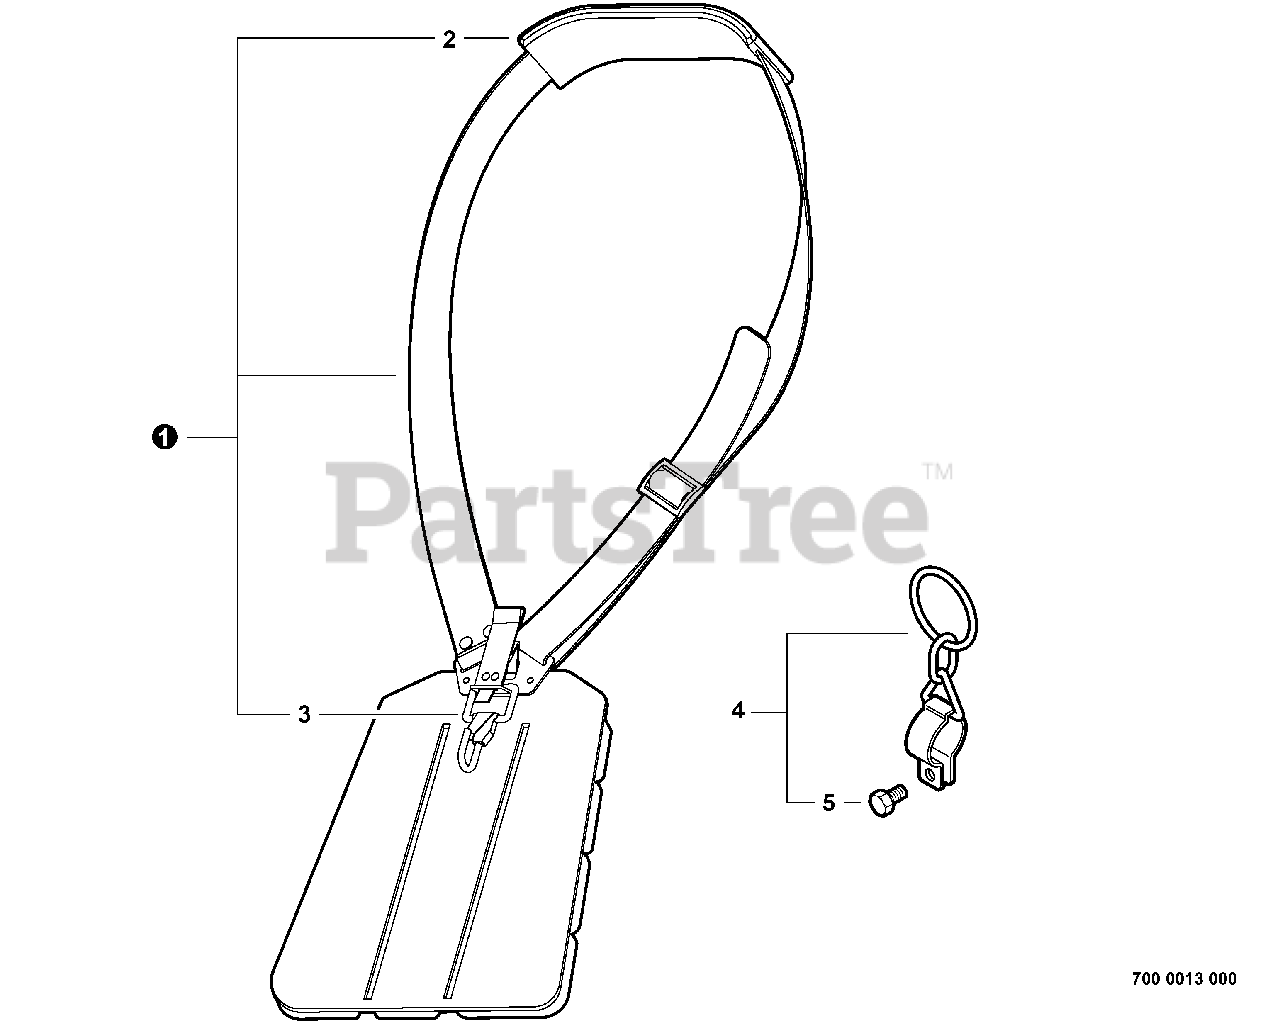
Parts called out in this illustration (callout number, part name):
1	HARNESS ASSY, BRUSHCUTTER
2	PAD, SHOULDER
3	HOOK, SNAP
4	HANGER SET, HARNESS
5	BOLT 5×12
